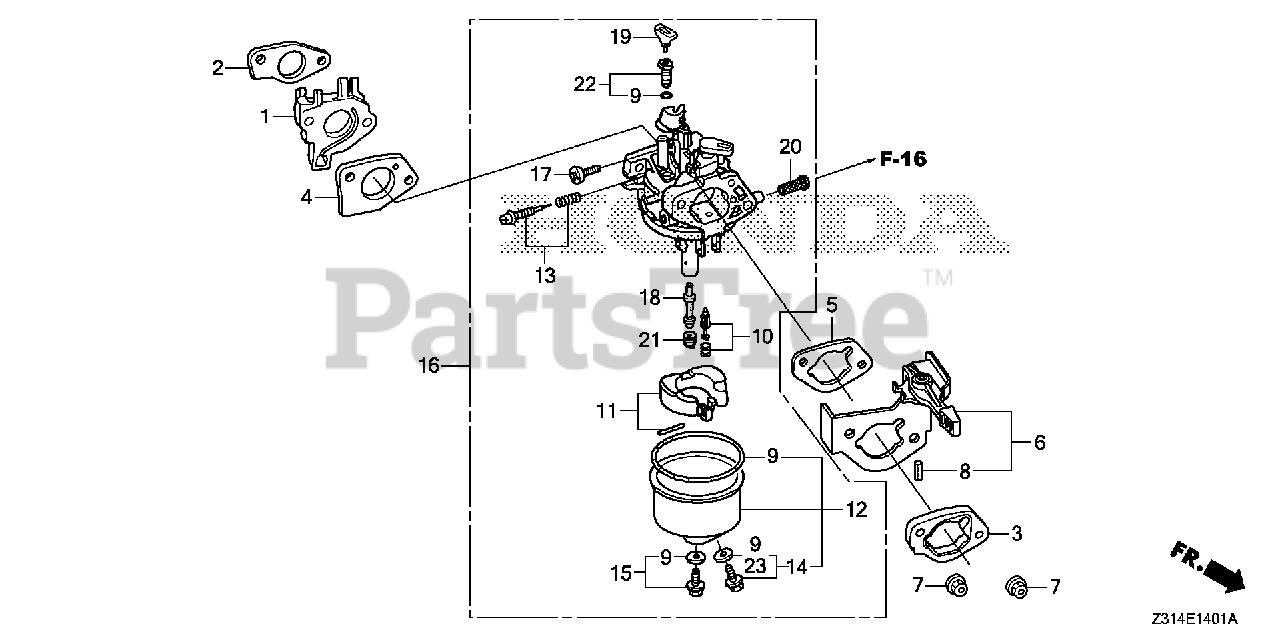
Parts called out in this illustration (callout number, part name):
1	INSULATOR, CARBURETOR
2	GASKET, CARBURETOR INSULATOR
3	SPACER, CARBURETOR
4	GASKET, CARBURETOR
5	GASKET, AIR CLEANER
6	BASE, CHOKE
7	NUT, FLANGE (6MM)
8	PIN, SPRING (2X12)
9	GASKET SET
10	VALVE SET, FLOAT
12	CHAMBER SET, FLOAT
14	SCREW SET, DRAIN
15	SCREW SET
16	CARBURETOR ASSY. (BE95A A)
17	SCREW, THROTTLE STOP
18	NOZZLE, MAIN
19	COLLAR, SETTING
20	SCREEN, FUEL STRAINER
21	JET, MAIN (#98)
21	JET, MAIN (#102)
21	JET, MAIN (#105)
22	JET SET, PILOT (#40)
23	WASHER, PLAIN (6.2X10.7 DRAIN)
